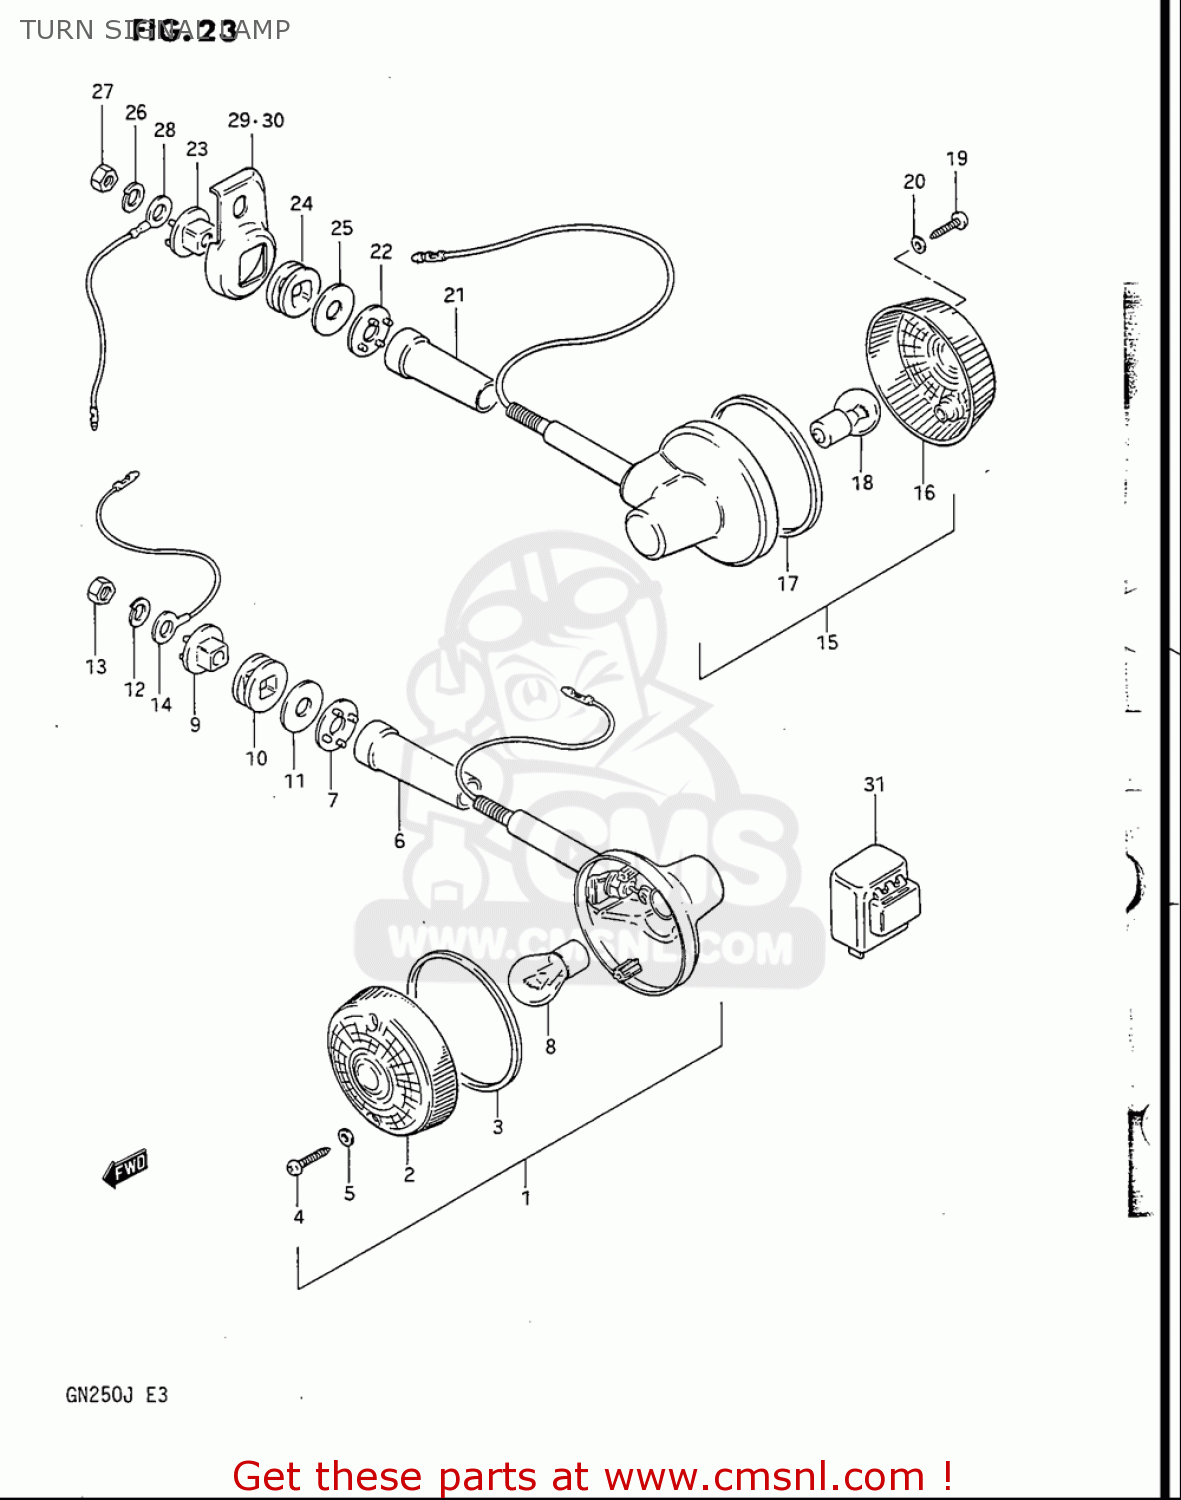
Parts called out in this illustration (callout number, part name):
1	LAMP ASSY,TURNSIGNAL
2	LENS
3	GASKET (NAS)
4	SCREW
5	GASKET (NAS)
6	COVER,STAY
7	CUSHION
8	BULB(12V23W,STANLEY,A4577A)
9	SPACER
10	CUSHION
11	WASHER(10.5X30X2.3)
12	WASHER,LOCK
13	NUT
14	LEAD WIRE,EARTH
15	LAMP ASSY,RR TURNSIGNAL
16	LENS
17	GASKET (NAS)
18	BULB(12V23W,STANLEY,A4577A)
19	SCREW
20	GASKET (NAS)
21	COVER
22	CUSHION
23	SPACER
24	CUSHION
25	WASHER(10.5X30X2.3)
26	WASHER,LOCK
27	NUT
28	LEAD WIRE,EARTH
31	RELAY ASSY,TURNSIGNAL
